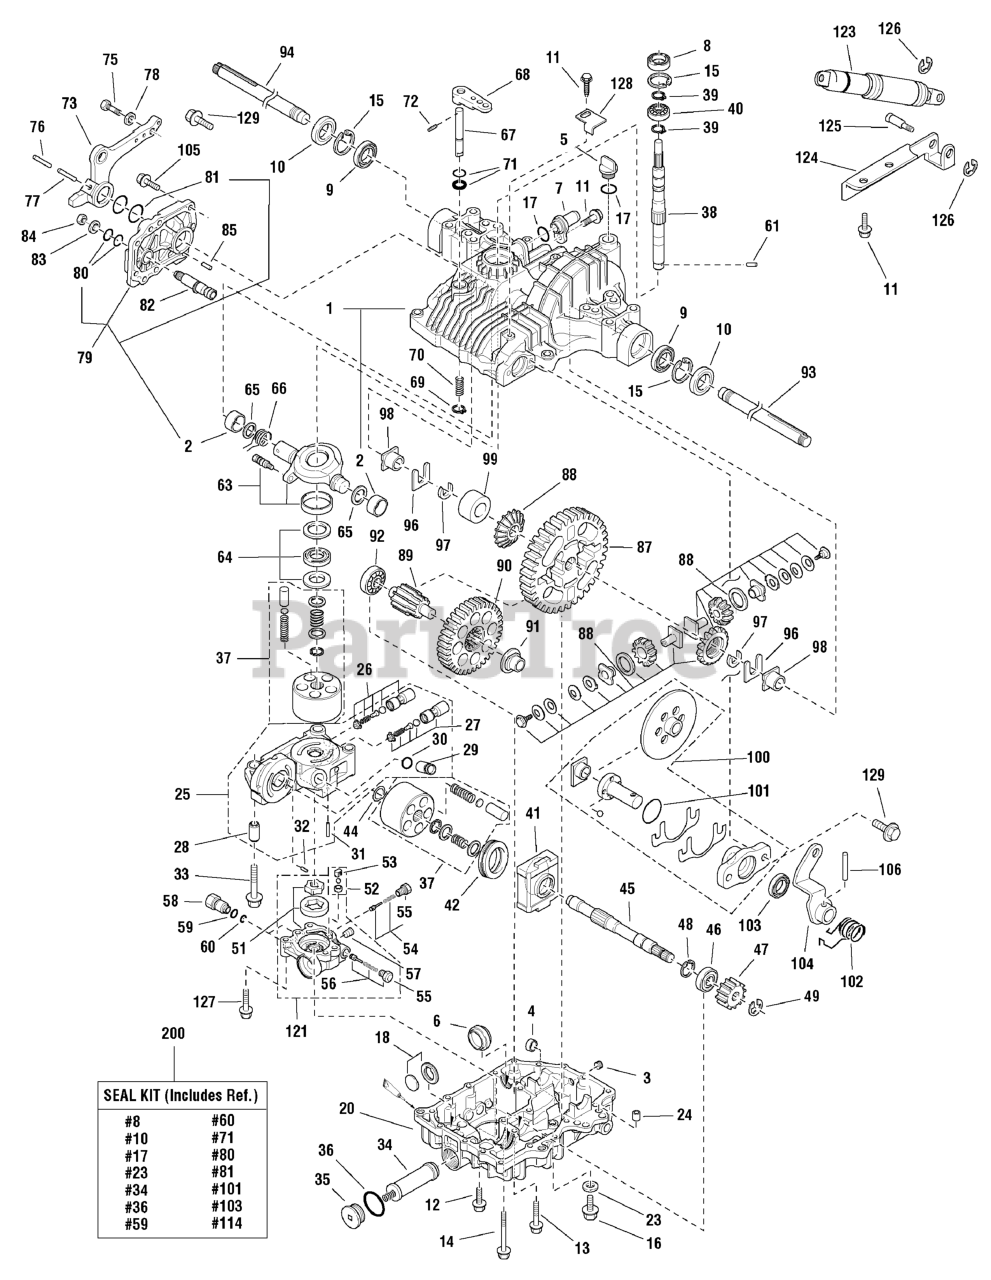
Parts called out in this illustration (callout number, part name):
1	*UPPER HOUSING, Complete
3	TAPER PLUG, 1/8
5	CAP, Oil, 20
6	FILTER
9	BEARING
10	SEAL
11	SCREW, Tapping, 8 x 25
15	RING, 47
16	BOLT, 10 x 12
17	PACKING, P18
18	MAGNET, Complete
20	LOWER HOUSING, Complete
23	WASHER, Seal 10
25	*CENTER CASE, Complete
26	*VALVE, (A-1 SET)
27	*VALVE, (A-2 SET)
30	PACKING
34	FILTER
35	CAP, (M40)
37	*CYLINDER BLOCK, Complete
38	PUMP SHAFT
39	RING, 17
40	BEARING, 6303
41	*HOUSING
45	*SHAFT MOTOR
46	BEARING 6004 SH2 U
47	*MOTOR GEAR
51	*PUMP CASE, Complete
52	*3RD CHECK, Complete
53	*HOLDER, (Seat)
54	*VALVE, (Imp Complete)
55	*PLUG
56	*VALVE, (Charge Complete)
58	CONNECTOR
59	O-RING
61	PIN, 3.2 x 21
63	*SWASH PLATE, Complete
64	*BEARING, Complete
65	*WASHER
66	*SPRING (N/C)
67	*SHAFT (BYPASS)
68	*LEVER (BYPASS)
69	RING
70	SPRING
71	PACKING
73	CONTROL LEVER
76	PIN, 6.0A x 50
77	PIN, 3.5A x 50
78	WASHER, 10
79	*SIDE COVER SET
82	*FULCRUM, (ECCENT)
87	*FINAL GEAR
88	DIFFERENTIAL GEAR KIT
89	*SHAFT, (F PINION)
90	*REDUCTION GEAR
93	*AXLE SHAFT, Left
94	*AXLE SHAFT, Right
96	THRUST WASHER
97	RING
98	*BUSHING
99	*COLLAR, (Diff. Lock)
100	BRAKE KIT
102	SP, (RETURN)
104	*ARM, (BRAKE)
121	PUMP CASE S/A
123	SHOCK ABSORBER
128	STOPPER, Brake
200	SEAL KIT, K71H, E, J, L
201	*KIT, Repair
